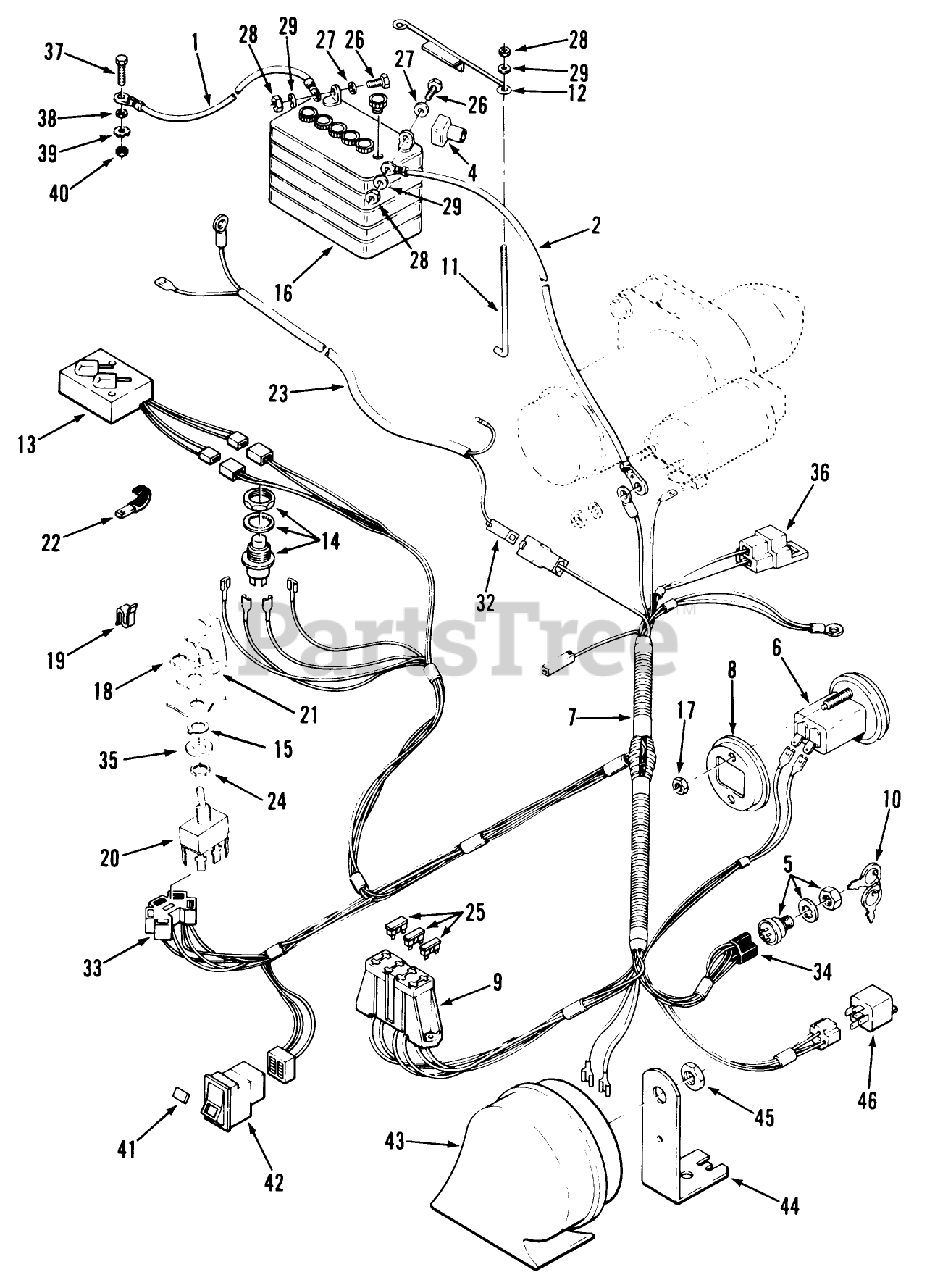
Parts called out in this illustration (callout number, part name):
1	WIRE -BLACK
2	ASS'Y-WIRE BATTERY
4	Boot
5	Ignition Switch (Includes 101884 Nut)
6	Hourmeter (Includes item 8)
7	MAIN-HARNESS & DIAG
8	BRKT-GAUGE MOUNTING
9	AUTO-FUSEBLOCK TERM
10	Key
11	HOOK-BATTERY RETAIN
12	HOLDDOWN-BATTERY
13	SWITCH-ASS'Y NEUTRAL
14	SWITCH-PLUNGER
15	TAB-WASHER
16	Battery
17	Hex Nut
19	CLIP-CABLE
20	SWITCH-ELECT CLUTCH
21	COVER-PTO SWITCH
22	CLIP
23	ENG WIRING HARNESS
24	NUT-HEX, SPECIAL
25	FUSE-BLADE, 15 AMP
26	Bolt
28	Nut
29	Washer
32	MALE CONNECTOR
33	CONNECTOR 5 WAY
34	CONNECTOR-5 WAY-SERV
35	WASHER
36	CONNECTOR BODY
37	Bolt
39	LCKWSHR 1/4 INT TTH
40	Nut
41	LENS-ENG TEMP
42	SWITCH-TEST
44	BRACKET-HORN
45	Nut 1/2-20" (Part of item 43)
46	RELAY
